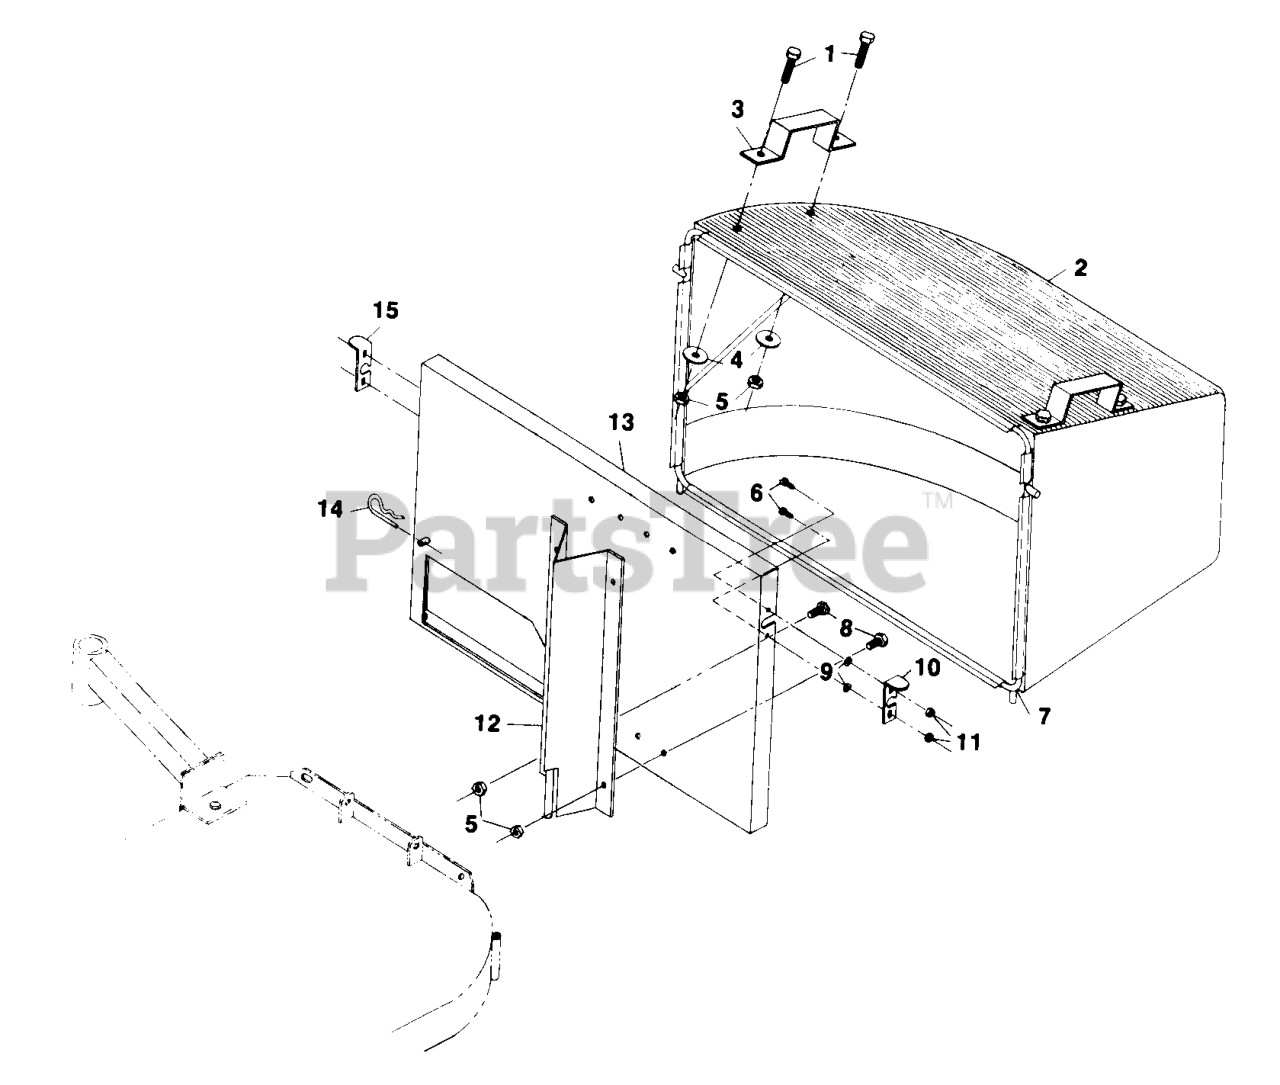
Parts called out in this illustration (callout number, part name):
7	FRAME-CATCHER
9	WASHER-SPRING
10	LATCH-CATCHER, RH
14	PIN-COTTER
15	LATCH-CATCHER, LH
